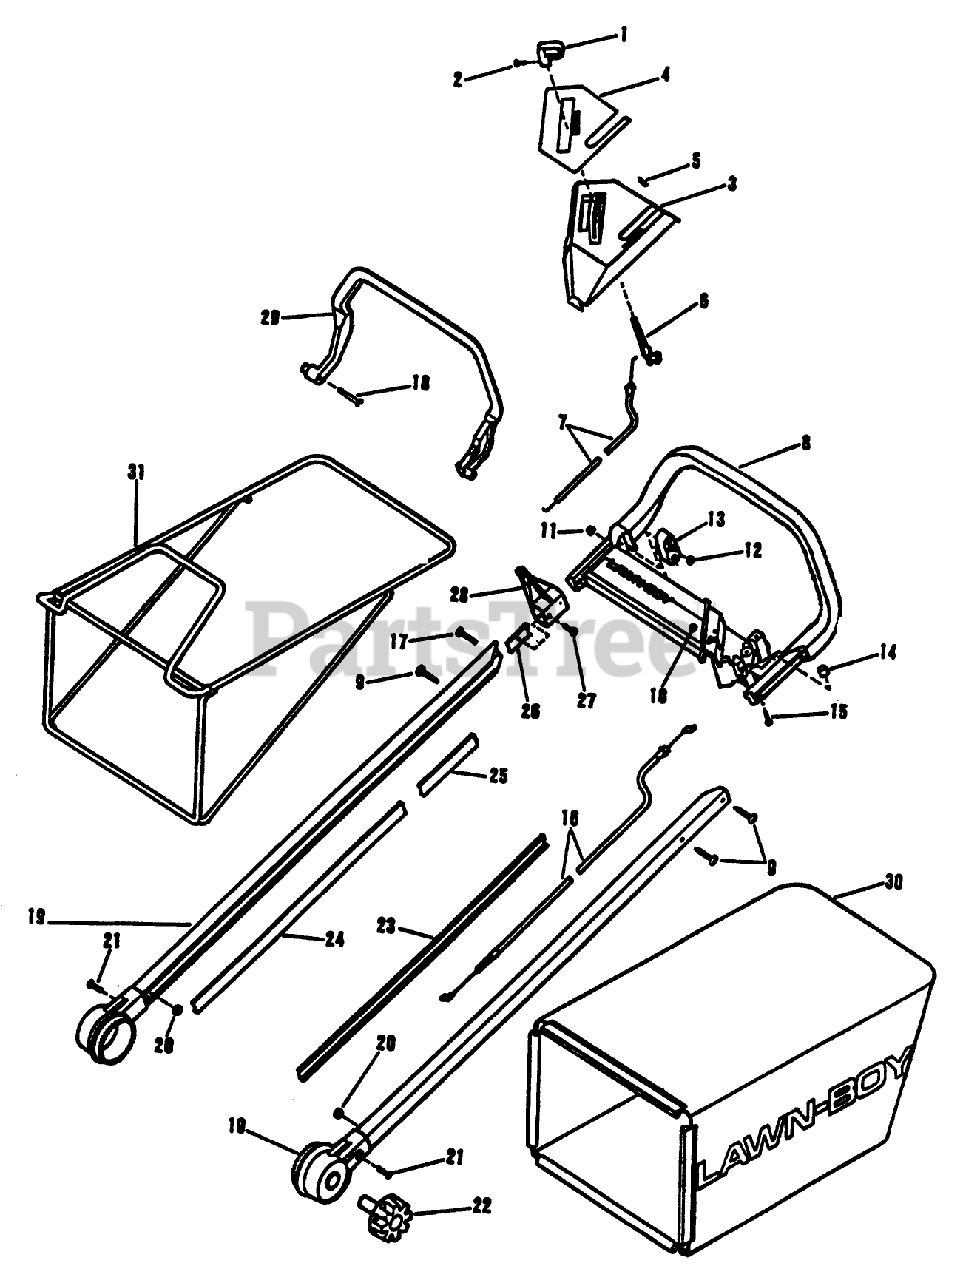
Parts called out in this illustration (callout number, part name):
11	LOCKNUT FLAN
12	LOCKNUT E
13	BLOCK BAIL PL
16	CABLE ASSEMBLY
17	SCREW-TRUSS
19	HANDLE SHAFT AY
20	LOCKNUT FLAN
22	KNOB-HDLE MT.ASM*B
23	INSERT - HANDLE
